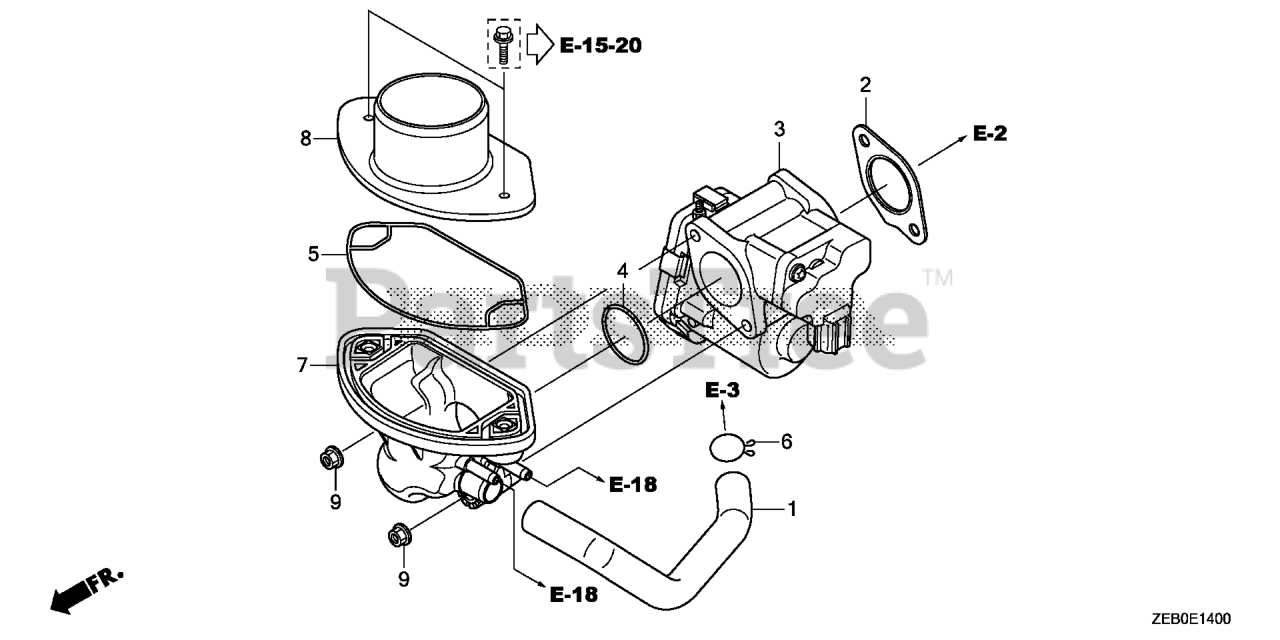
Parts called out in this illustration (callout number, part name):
1	TUBE, BREATHER
2	GASKET, THROTTLE BODY
3	BODY ASSY., THROTTLE
4	GASKET, AIR CLEANER
5	SEAL, AIR CLEANER HOUSING
6	CLIP, BREATHER TUBE
7	ELBOW, AIR CLEANER
8	JOINT, CONNECTING TUBE
9	NUT, FLANGE (6MM)
